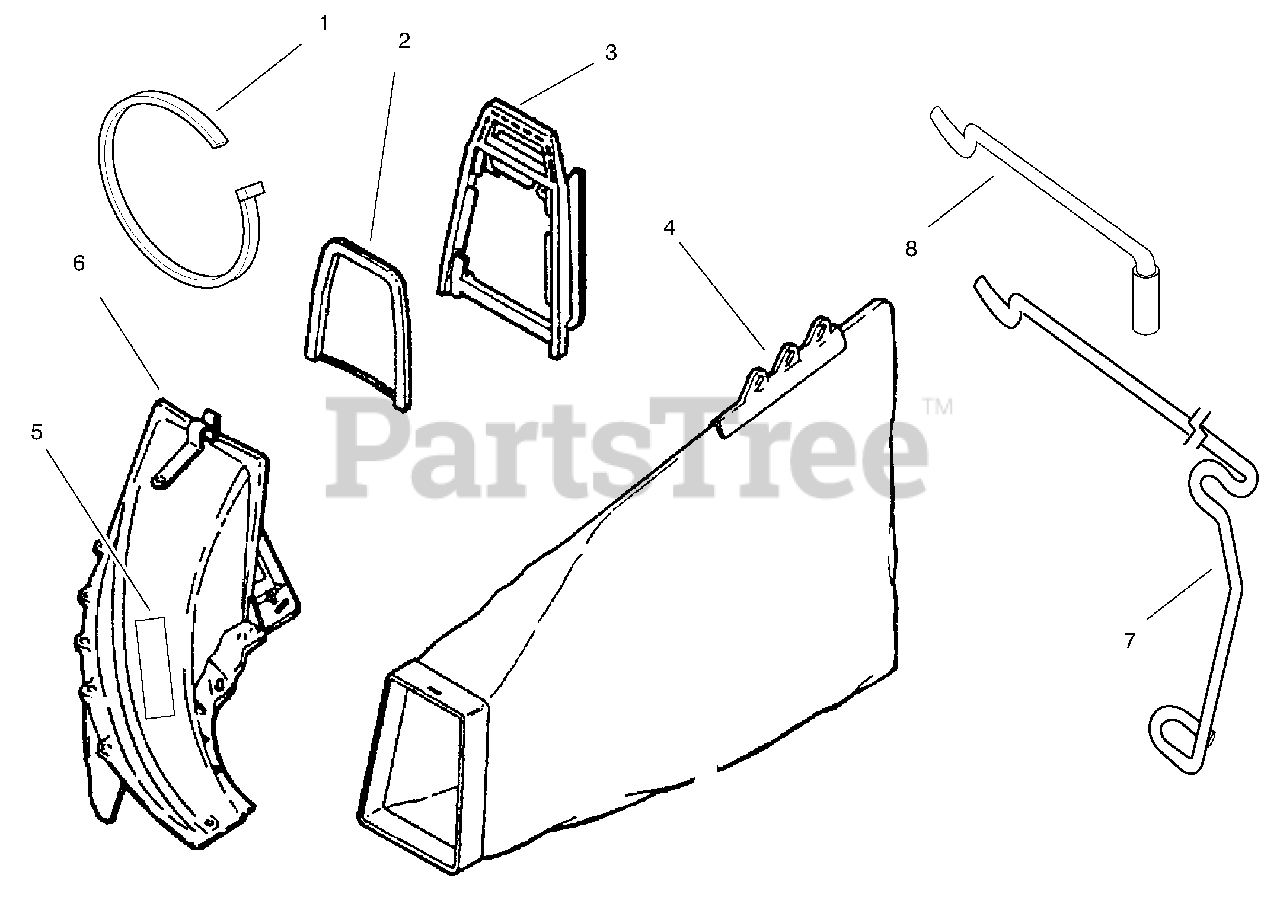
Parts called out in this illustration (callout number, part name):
1	Strap-Tie
2	Brace-Chute
3	Adaptor-Chute
4	Bag-Grass (Incl Ref. #1 & 3)
5	Decal-Danger
6	Chute Assembly
7	Rod-Grass Bag
8	Adapter Asm
